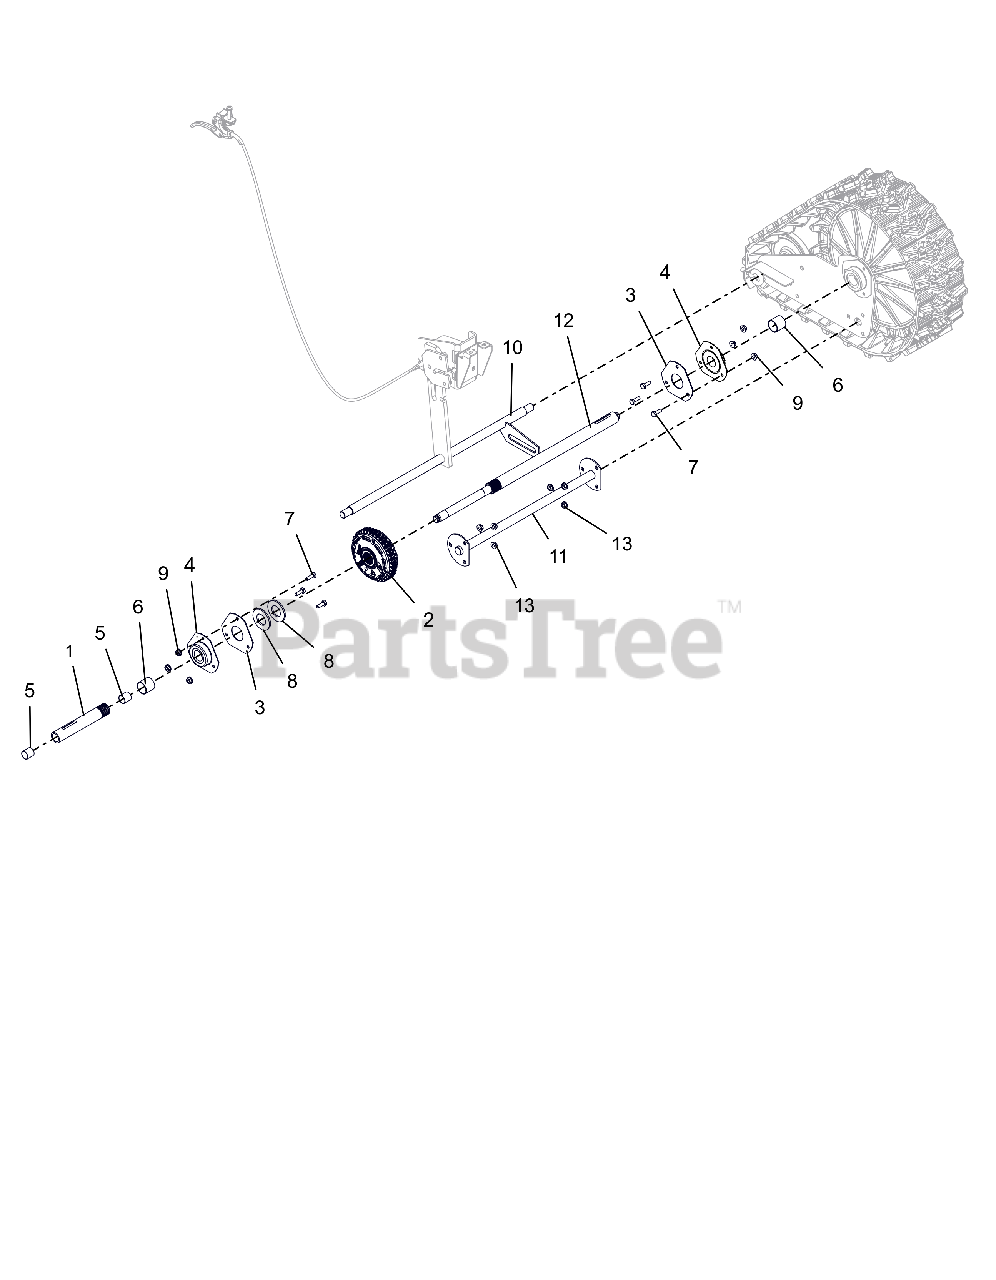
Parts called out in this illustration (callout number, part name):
1	AXLE, SHORT-W/BUSHINGS
2	DIFFERENTIAL, AUTOMATIC
3	PLATE, BEARING SPACER
4	BRG-FLG 1.003/1.000 3 BOLT
5	BSHG-SLV .706X.764X.75 BRZ
6	BSHG-SLV, 1.012X1.125X1.00
7	BLT, HEX .25-20X.75 G5 ZCC
8	WSHR, FLT 1.062X2.000X.134 ZCC
9	NUT-LK-CTR-FLG .25-20 ZC120
10	AXLE, REAR-BWT WLDMT
11	SUPPORT, FRONT-BWT
12	AXLE, LONG-TRACK DIFFERENTIAL
13	NUT-LK-TOP-FLG .250-20 GF ZCC
